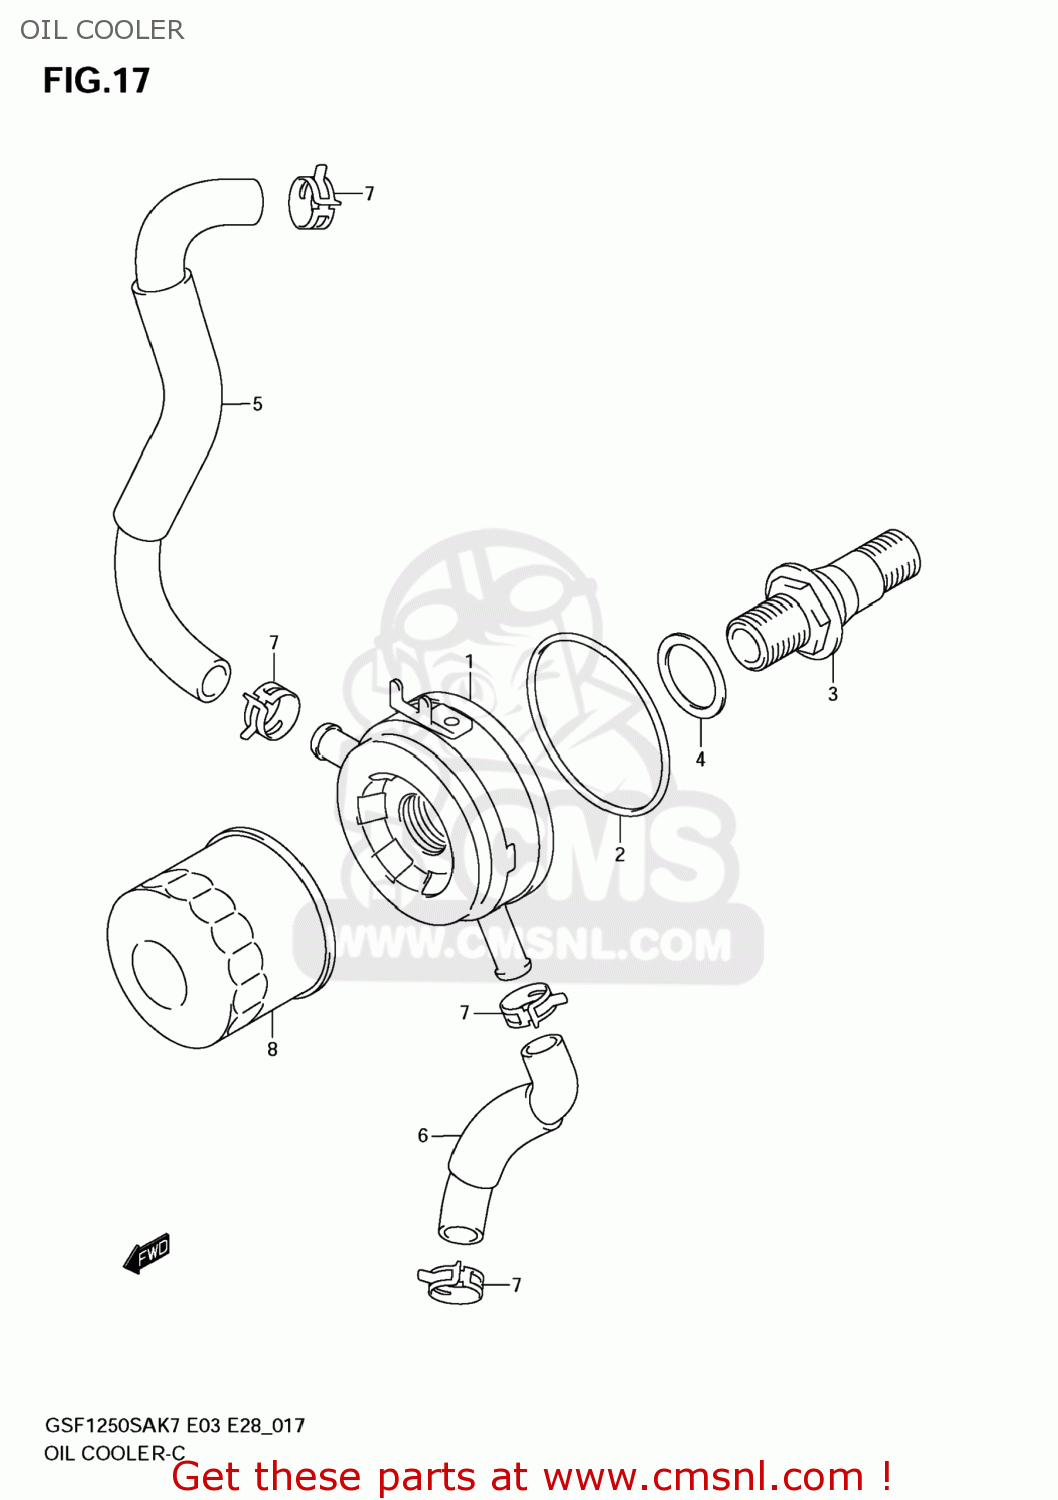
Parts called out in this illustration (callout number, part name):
1	COOLER ASSY,OIL
2	O RING(D:3.1,ID:63.9)
3	BOLT,OIL COOLER UNION
4	SHIM(25X34X0.7)
5	HOSE,OIL COOLER WATER INLET
6	HOSE,OIL COOLER WATER OUTLET
7	CLIP
8	FILTER ASSY,EN
